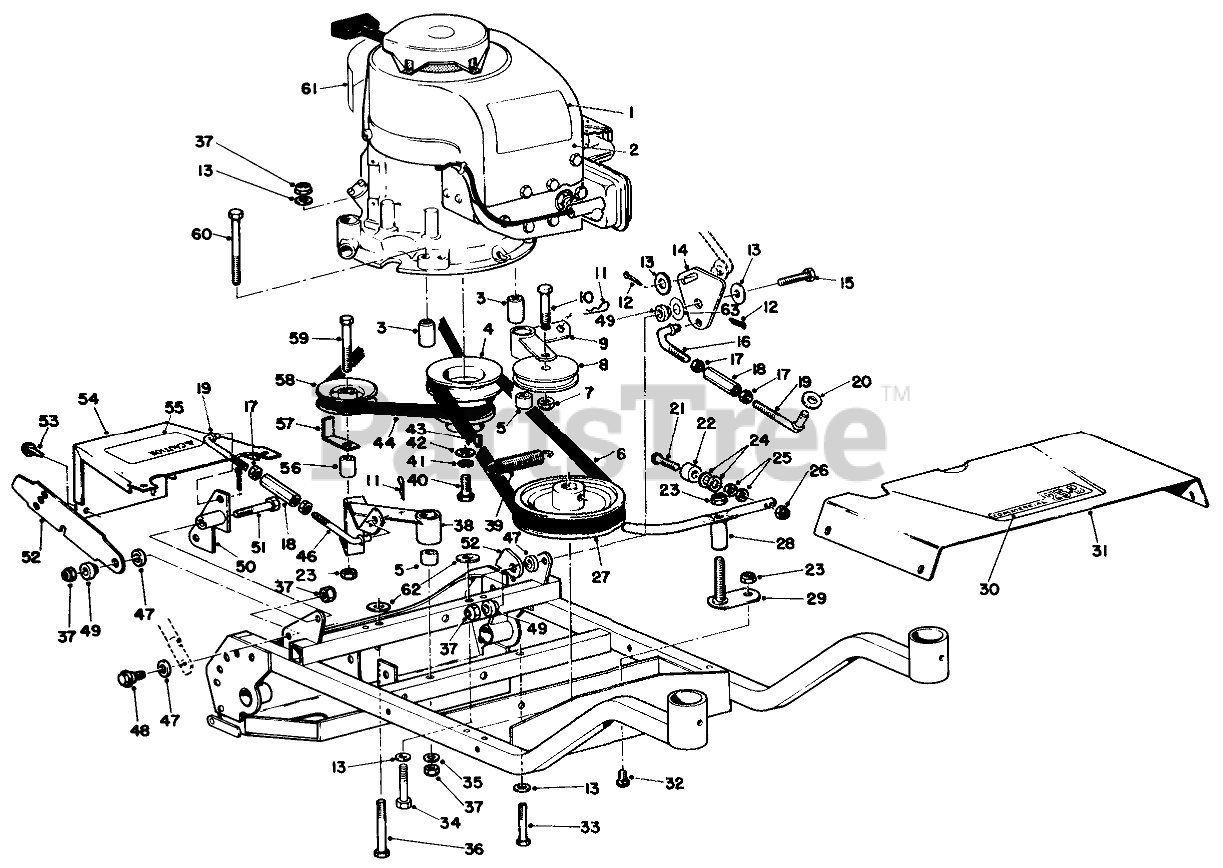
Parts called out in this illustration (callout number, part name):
1	Decal
2	Engine
3	ENGINE PIVOT SPACER
4	ENGINE PULLEY RO
5	BUSHING
7	Nut
8	PULLEY B
9	Arm and Bushing (Incl. Ref. #5)
10	Screw
11	PIN-COTTER
12	PIN-COTTER
13	WASHER-PLAIN
14	CUTTR BELLCRANK WA R
15	5/16-18 X 1-3/4 SCREW
16	CUTTER LINK
17	NUT-KEPS
18	CONTROL ROD SLEEVE
19	LINK CONTROL ROD
20	WASHER
21	10-24X1-1/2 RND HD MS
22	BUMPER
23	NUT-HEX
24	WASHER-FLAT
25	NUT-HEX
26	NUT-LOCK, NI
27	DECK PULLEY R
28	Brake Arm
29	Base Pivot
30	DECAL
31	FRONT SHROUD R
32	SCREW-CARR
33	SCREW-HH
34	SCREW-HH
35	WASHER-LOCK/SP
36	SCREW-HH
37	Nut
38	Arm and Bushing (Incl. Ref #5)
39	EXTENSION SPRING
40	SCREW-HH
41	WASHER-LOCK
42	WASHER-FLAT
43	KEY-WOODRUFF
44	V-BELT
46	Control Rod
47	SPACER
48	SCREW-SHOULDER
49	PIVOT
50	TRACT BELLCRANK WA R
51	SCREW-HH
52	HANDLE LATCH
53	10-16 X 3/8 THDG SCREW
54	Rear Shroud
55	DECAL SAF INST
56	SPACER
58	IDLER PULLEY R
59	SCREW-HH
60	SCREW-HH
61	Decal
62	WASHER
63	WASHER
